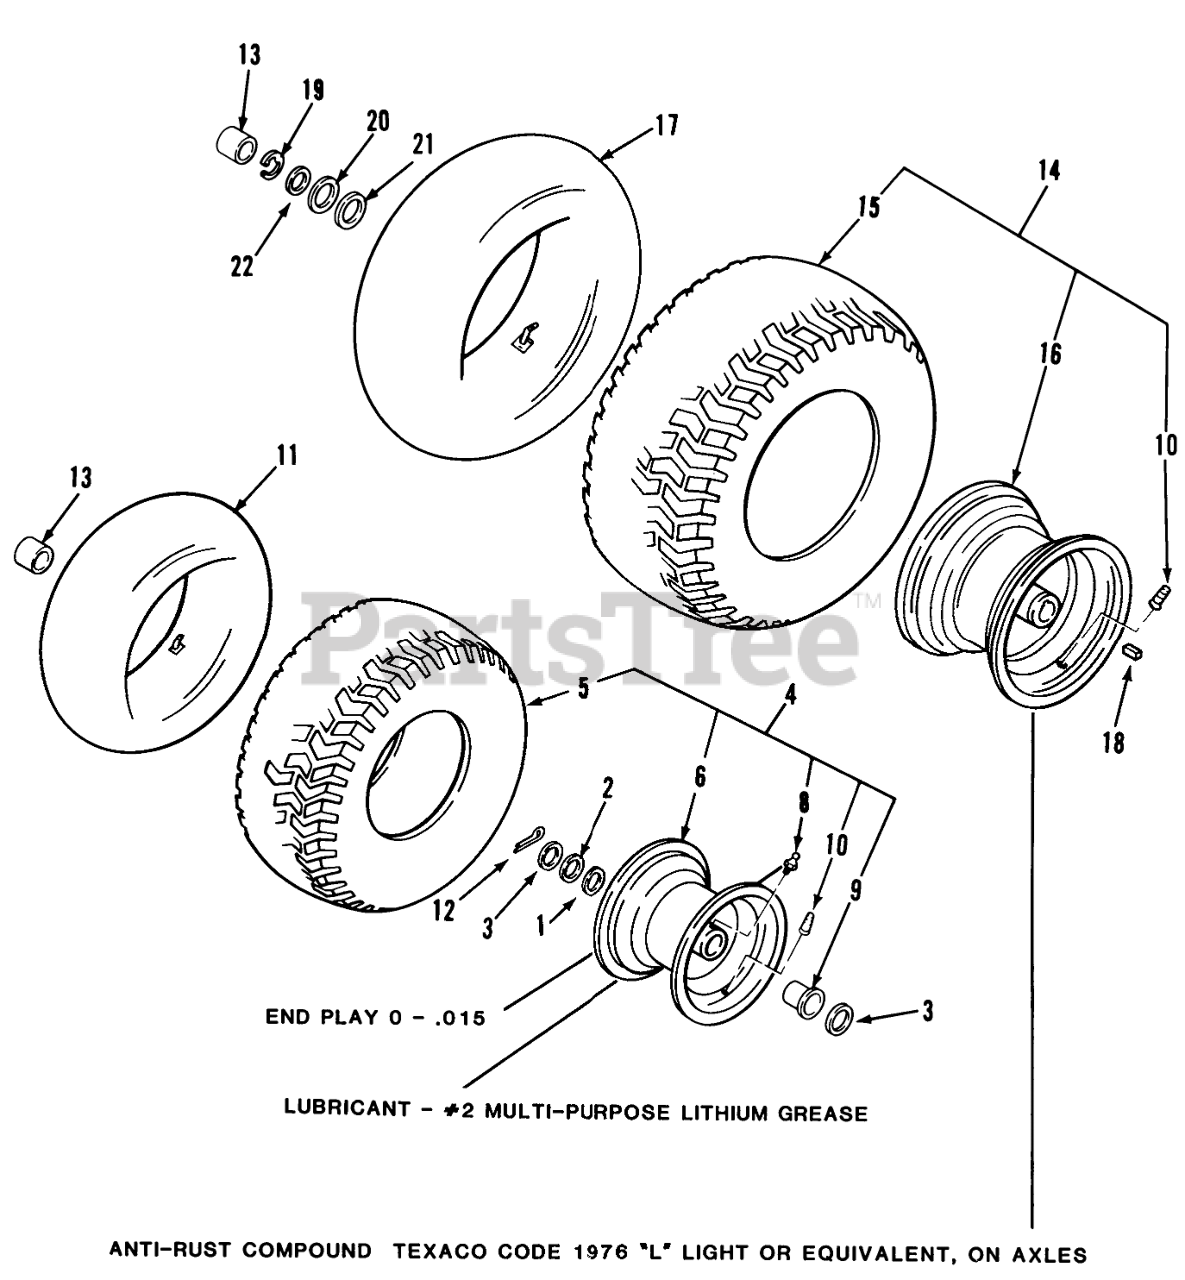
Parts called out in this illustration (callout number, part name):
1	WASHER-SHIM
2	WASHER
3	WASHER-FLAT
5	TIRE
6	ASS'Y-WHEEL
8	ZERK-GREASE
9	BUSHING-FLANGE
10	VALVE
12	COTTER PIN-4
15	TIRE 18 X 8.50 X 8
15	TIRE 18 X 9.50-8
16	ASSY-WHEEL
18	SQ KEY
20	WASHER-SHIM
21	WASHER
22	WASHER-FLAT
